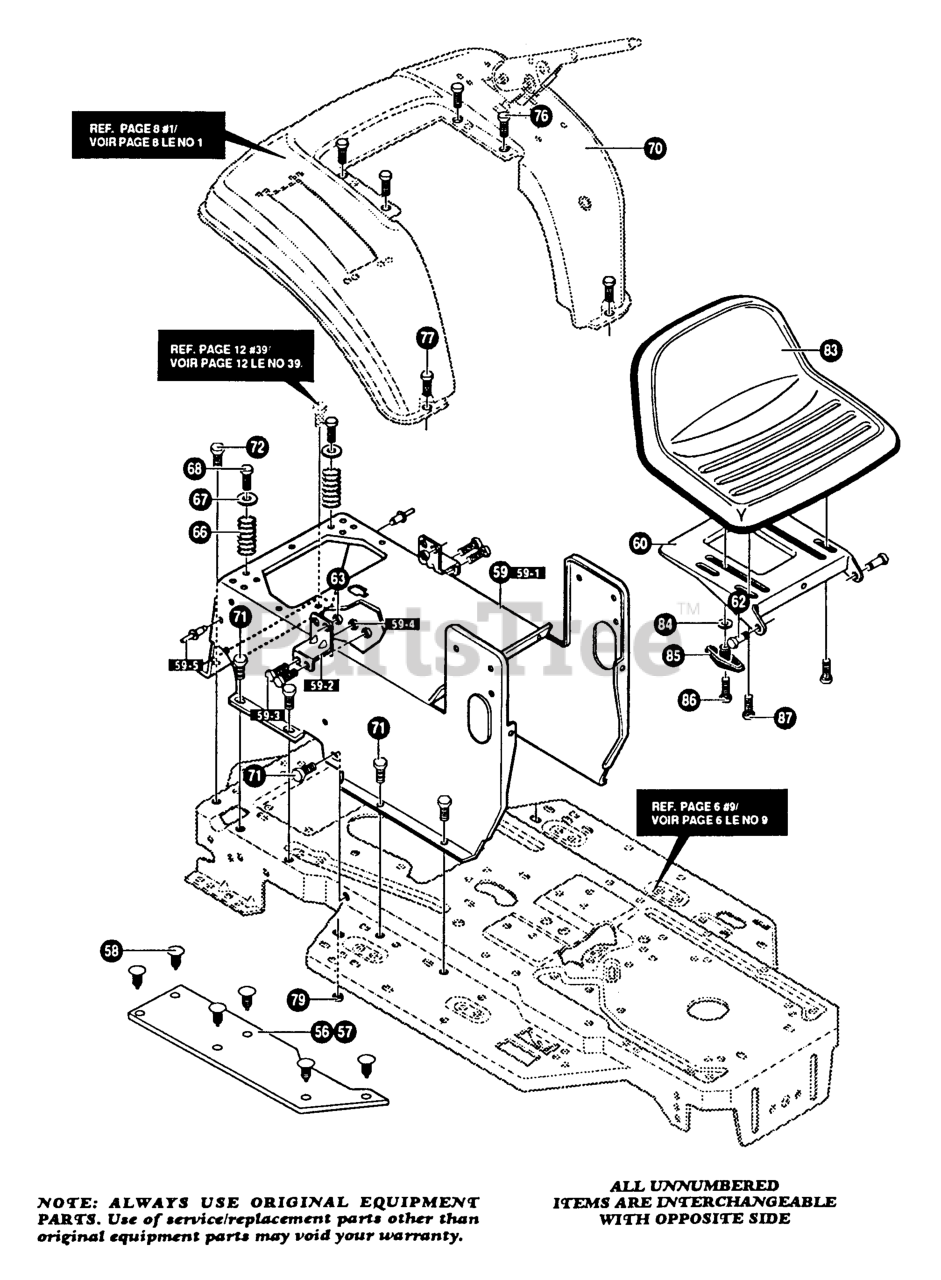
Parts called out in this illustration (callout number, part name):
56	FOOT PAD, LH
57	FOOT PAD, RH
58	FASTENER
59	ASSEMBLY, CONSOLE
59-2	BRACKET
59-3	SCREW
59-5	RIVET
60	PLATE, SEAT
66	SPRING, SEAT
67	WASHER
70	ASSEMBLY, FENDER
72	SCREW
84	WASHER
85	HANDLE
